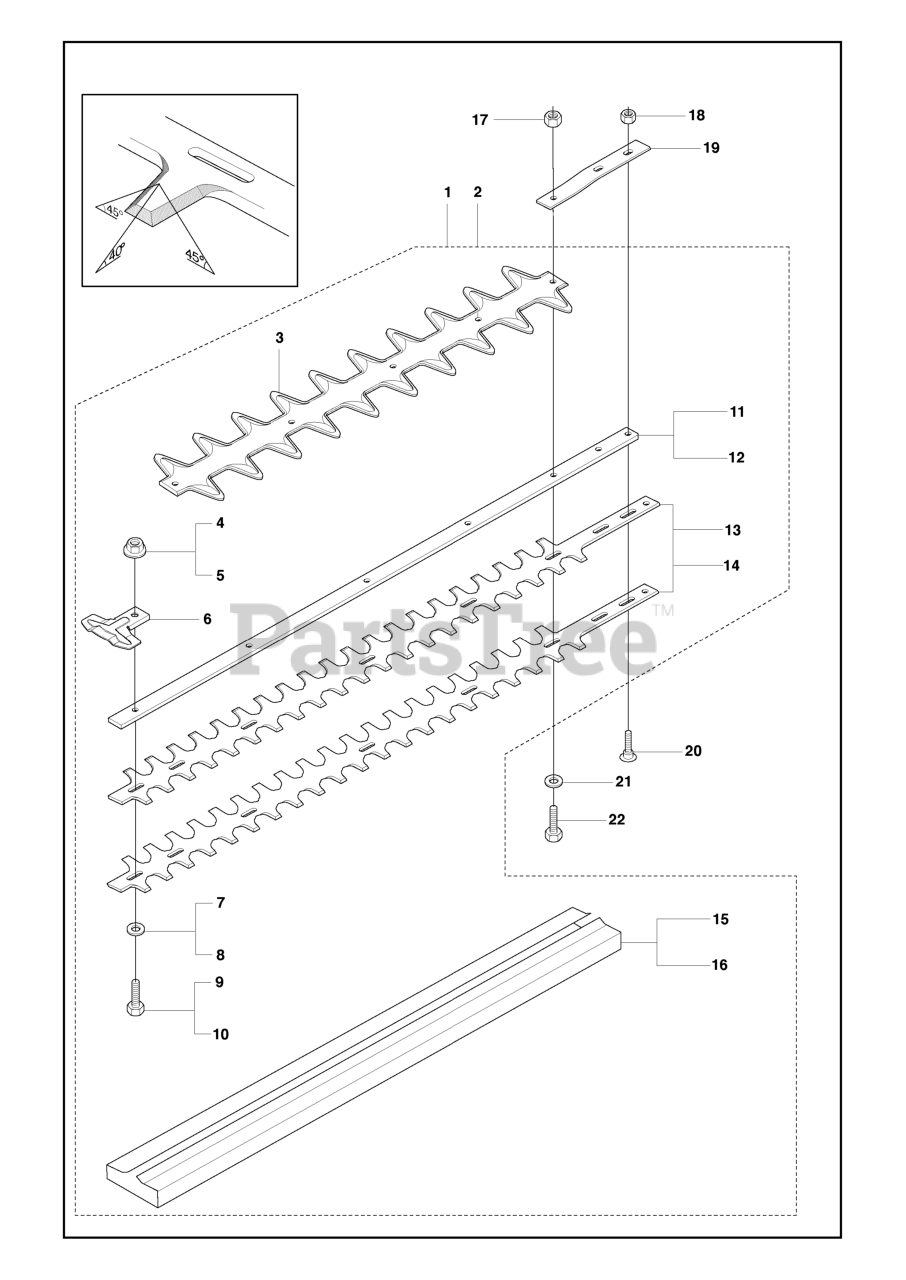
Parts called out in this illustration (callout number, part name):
1	GEAR HOUSING
2	BALL BEARING 6002-2RS1
6	GREASE NIPPLE
7	CLUTCH YOKE
8	CLUTCH CPL
12	CLUTCH DRUM
13	SCREW W/ LOCKING FLUID
27	CONNECTING ROD
30	BALL BEARING
31	WASHER 15X24
